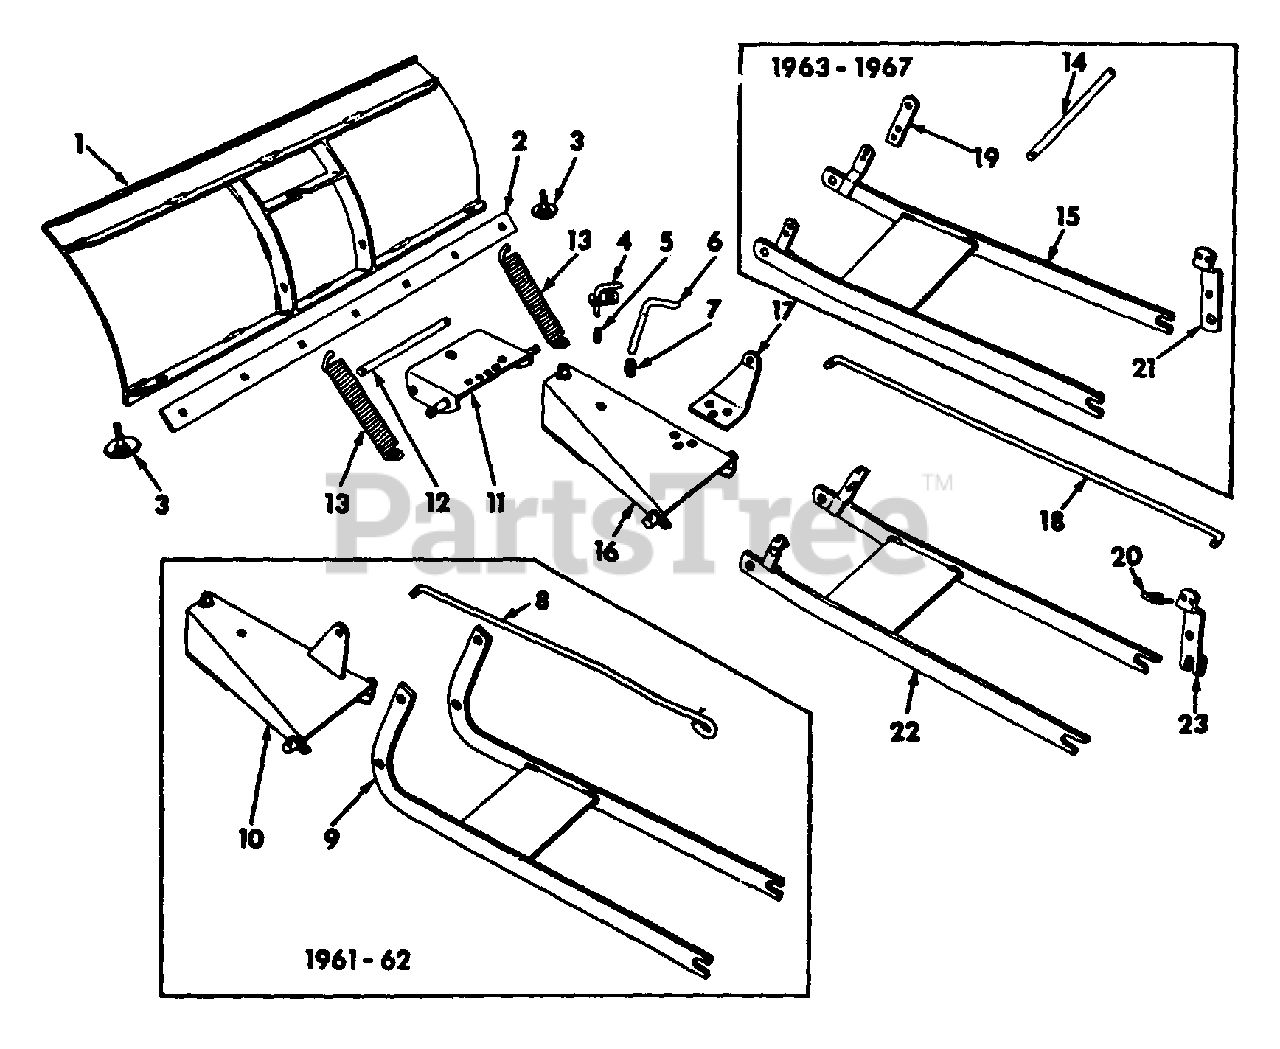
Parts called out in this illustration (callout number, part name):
1	BLADE ASSY -42 INCH-
2	EDGE, BLADE CUTTING -42 INCH-
3	SHOE ASSEMBLY, SKID
4	LOCK ASSEMBLY, SPRING TRIP
5	SPRING, COMPRESSION TYPE
6	PIN, ANGLING
7	SPRING, COMPRESSION TYPE
9	SUB-FRAME ASSY
10	FRAME ASSEMBLY, MAIN
11	FRAME ASSEMBLY, PIVOT
12	ROD, BLADE PIVOT
13	SPRING, EXTENSION TYPE
14	ROD, MOUNTING
15	SUB-FRAME ASSY.
16	FRAME ASSEMBLY, MAIN
18	ROD, LIFT
19	BRACE, EXTENSION
20	U-BOLT
21	BRACKET, LIFT
22	SUB-FRAME ASSY
23	BRACKET, LIFT
137180	PIN, 1/8 x 7/8 C-Z COTTER
137218	PIN, 5/32 x 1-1/4 C-Z COTTER
180112	SCREW, 5/16-18 x 2-3/4 C-Z HEX-HD CAP
180175	SCREW, 1/2-13 x 1-1/4 C-Z HEX-HD CAP
